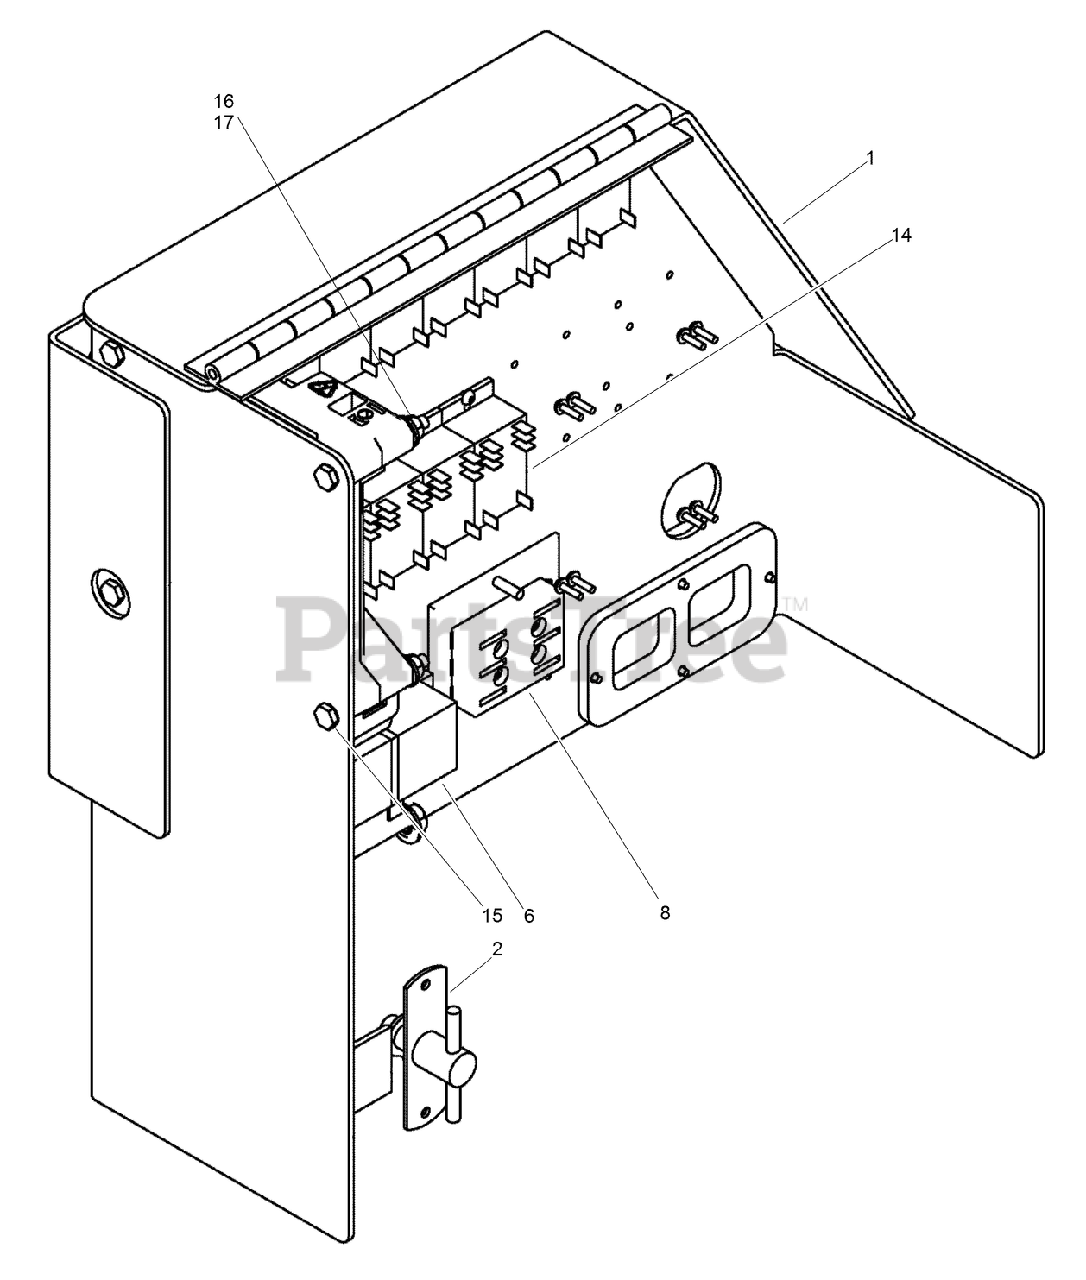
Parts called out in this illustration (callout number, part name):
1	BOX - Electrical
6	RELAY - Power, 12 VDC
8	FUSEHOLDER
14	RELAY - 2 Pole 12 VDC Panel Mount
15	BOLT - Hex Hd .250 x 2.50 GR8 PHC
16	WASHER-FLAT
17	NUT - Hex .250 - 20 GR5 ZND
